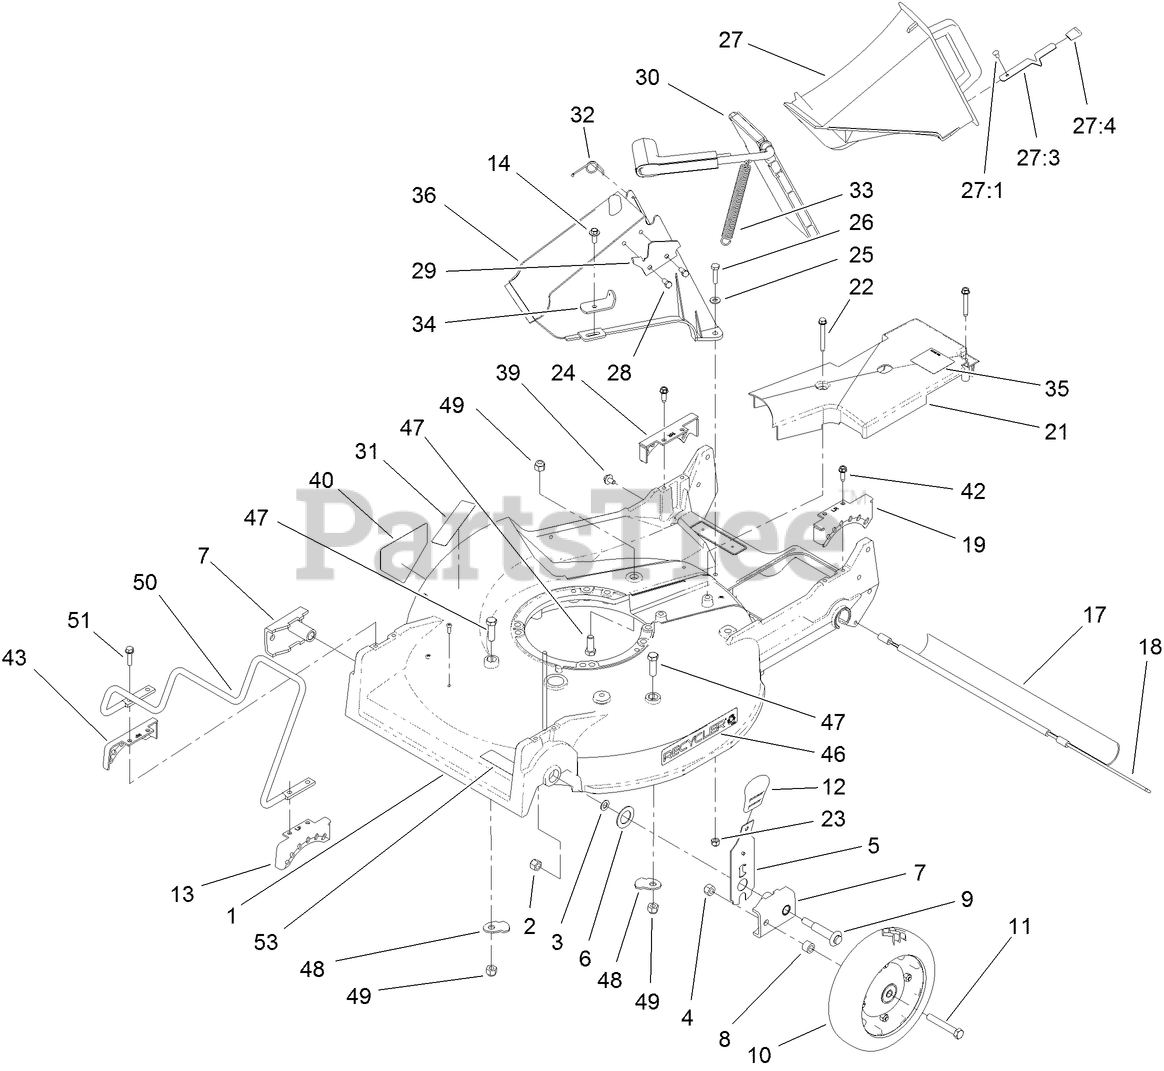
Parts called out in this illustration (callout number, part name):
1	HOUSING
2	NUT-LOCK
3	WASHER
4	NUT-LOCK, CONE
5	FRONT SPRING ARM ASM
6	WASHER-THRUST
7	ARM-PIVOT, FRONT
8	SPACER-WHEEL
9	SCREW-SHOULDER
10	WHEEL AND TIRE ASM
11	SCREW-HH
12	KNOB-HOC
13	QUADRANT-FRONT, LH
14	SCREW-HWH
17	SHIELD-TRAILING
18	ROD-SHIELD
19	QUADRANT-REAR, LH
21	COVER-BELT
22	SCREW-HWHTF
23	NUT-LOCK, NI
24	QUADRANT-REAR, RH
25	WASHER-FLAT
26	SCREW-HH
27	DISCHARGE PLUG ASM
27:1	RIVET-HEAD, FLAT
27:3	LATCH-PLUG, DISCHARGE
27:4	GRIP-LATCH
28	SCREW-PLASTITE
29	LATCH-PLATE
30	DISCHARGE DOOR ASM
31	DECAL-ARRESTER, SPARK
32	RETAINER-DOOR
33	SPRING-DOOR
34	BRACKET-SPRING
35	DECAL-GREASE
36	TUNNEL-DISCHARGE
39	SCREW AND WASHER ASM
40	DECAL-DANGER
42	SCREW-HWHTF
43	QUADRANT-FRONT, RH
47	SCREW-HH
48	SHIELD-RETAINER
49	NUT-LOCK, NI
50	GUARD-ENGINE
51	SCREW-HWHTF
53	DECAL-BLADE
